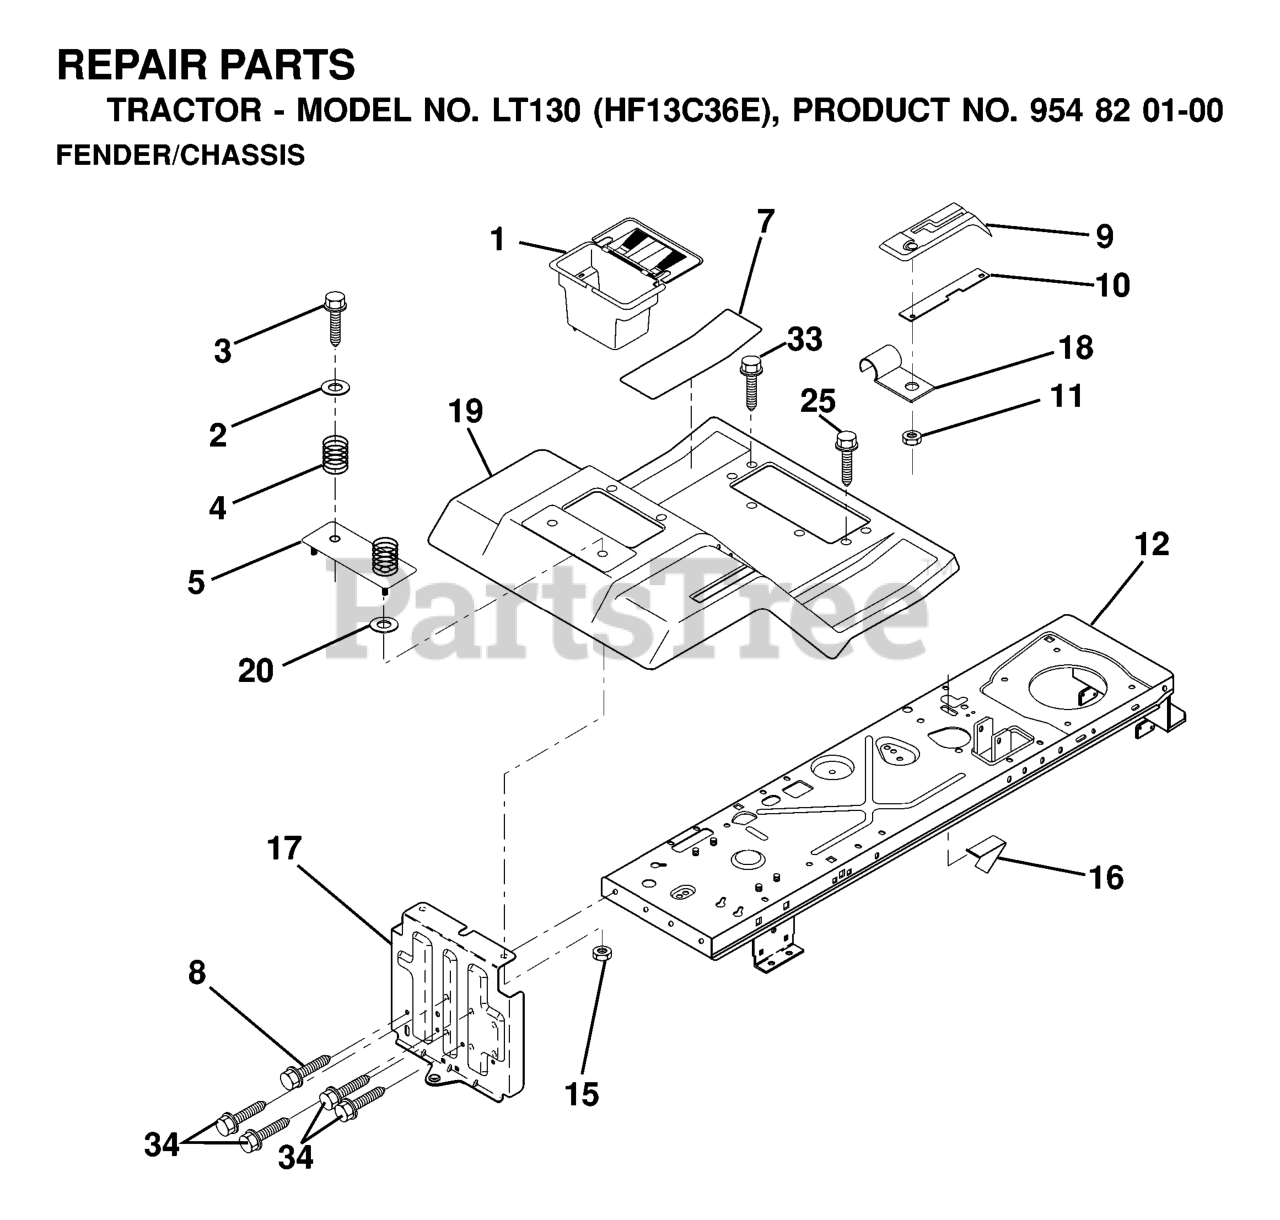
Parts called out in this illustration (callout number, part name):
1	CASE BATTERY MECH HINGE
2	WASHER
3	SCREW
4	SPRING COMPRESSION
5	PLATE ASM BATTERY
7	FOOTREST PAD
8	SCREW.THDROL.5/16-18X3/4.TTY
10	BAR, SHIFT LOCK
11	NUT.PUSH.3/16
15	Nut, Keps Blk Hex 1/4-20 UNC
16	SWITCH ACTUATOR
18	CLIP,INSULATOR
19	FENDER/FOOTREST
20	WASHER
25	Screw Tapping 5/16-18 Unc
33	Screw Hex Wsh Thdroll 5/16-18 x 1
34	SHOULDER BOLT 5/16-18TT
